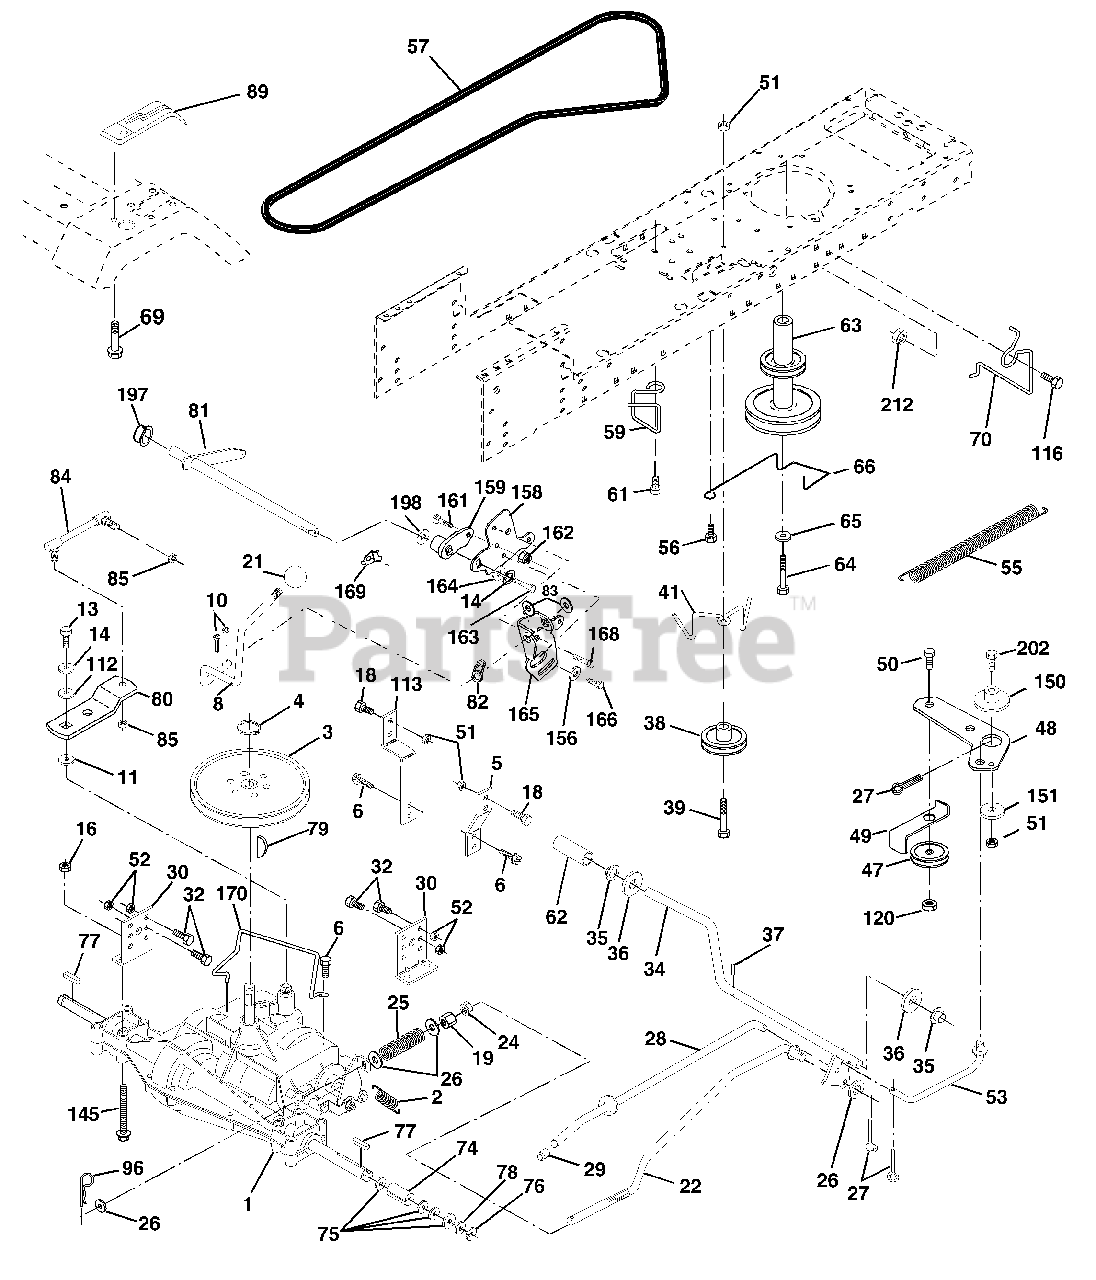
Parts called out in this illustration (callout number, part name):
2	Spring Return Brake T/a Zinc
3	Pulley Transaxle 18" tires
4	Ring Retainer # 5100-62
5	Strap Torque 30 Degrees
6	Screw 5/16-18 X 3/4
8	Rod Shifter Fender Adj Lt
10	Pin Cotter 1/8 X 1 Cad
11	Washer Plate Shf 388 Sq Hole
13	Bolt 1/4-28 Unf Gr 8 W/Patch
14	Washer Lock Hvy Helical 1/4
16	Nut Lock Hx W/Ins 5/16-18 Unc
18	Bolt, Fin Hex 3/8-16 UNC x 1 Gr. 5
19	Nut Lock 3/8-16 Unc
21	Knob
22	Rod Brake Blk Zinc 26 840
24	Nut Hex Jam 3/8-16 Unc
25	Spring Rod Brake 2 00 Zinc
26	Washer 13/32 X 13/16 X 16 Ga
27	Pin Cotter 1/8 X 3/4 Cad
28	Rod Brake Parking LT/YT
29	Cap Brake Parking
30	Bracket Mtg Transaxle
32	Bolt Hex Hd 5/16-18unc X 3/4
34	Shaft Asm Pedal Foot
35	Bearing Nylon Blk 629 Id
36	Washer 21/32 X 1 X 16 Ga
37	Pin Roll 3/16 X 1"
38	Pulley Idler Composite
39	Bolt Fin Hex 3/8-16 X 3
41	Keeper Belt Idler
47	Pulley Idler V Groove Plastic
48	Bellcrank Asm
49	Retainer Belt Style Spring
50	Bolt Hex Hd 3/8-16unc X 1-1/2
51	Nut Crownlock 3/8-16 Unc
52	Nut Crownlock 5/16-18 Unc
53	Link Clutch
55	Spring Return Clutch 6 75
56	Screw 3/8-16 X 1-1/4
57	V-Belt Ground Drive
59	Keeper Belt Span Ctr
61	Screw 3/8-16 x .875
62	Cover Pedal Blk Round
63	Engine Pulley LT/YT
64	Bolt Hex
65	Washer Lock Hvy Hlcl Spr 7/16
66	Keeper Belt Engine Foolproof
69	Screw Hex Wsh Hi-Lo 1/4-1/2 Unc
70	Guide Belt Mower Drive RH
74	Spacer Axle
75	Washer 25/32 X 1 1/4 X 16 Ga
76	E-ring #5133-75
77	Key Square 2 0 X 1845/ 1865
78	Washer 25/32 X 1-5/8 X 16 Ga
79	Key Woodruff
80	Arm Shift
81	Shaft Asm Cross Tapered 20"t
82	Spring Torsion T/a
83	Washer 17/32 X 3/4 X 16 Ga
84	Link Transaxle
85	Nut Lock Center 1/4 - 28 FNTHD
89	Console Shift STLT
96	Retainer Spring
112	Washer 9/32 x 3/4 x 10 Ga.
113	Strap Torque Lh
116	Bolt Rdhd Sq Neck 3/8-16 x 1
120	Nut Lock Flg 3/8-16
145	Bolt Hex 5/16-18 Gr. 5
150	Spacer Retainer
151	Washer 13/32 x 2 x 10
156	Washer Srrted 5/16 ID x 1.125
158	Bracket Shift Mount
159	Hub Tapered Flange Shift lt
161	Bolt Rdhd Sqnk 1/4-20 x 3/4 Gr 5
162	Nut Crownlock 1/4-20 Unc
163	Bolt Hex Fin 1/4-20 Unc x 1 Gr 5
164	Washer 5/8 x .281 x 10 Ga
165	Bracket Pivot Lever
166	Screw 5/16-18 x 5/8
168	Bolt Shoulder 5/16-18 x .561
169	Plate Fastening Lt
170	Keeper Belt Transaxle
197	Nyliner Snap-In
198	Washer Nyliner
202	Bolt Carr. Sh 3/8-16 x 1-3/4 Gr. 5
212	Nut Hex Flange Lock
